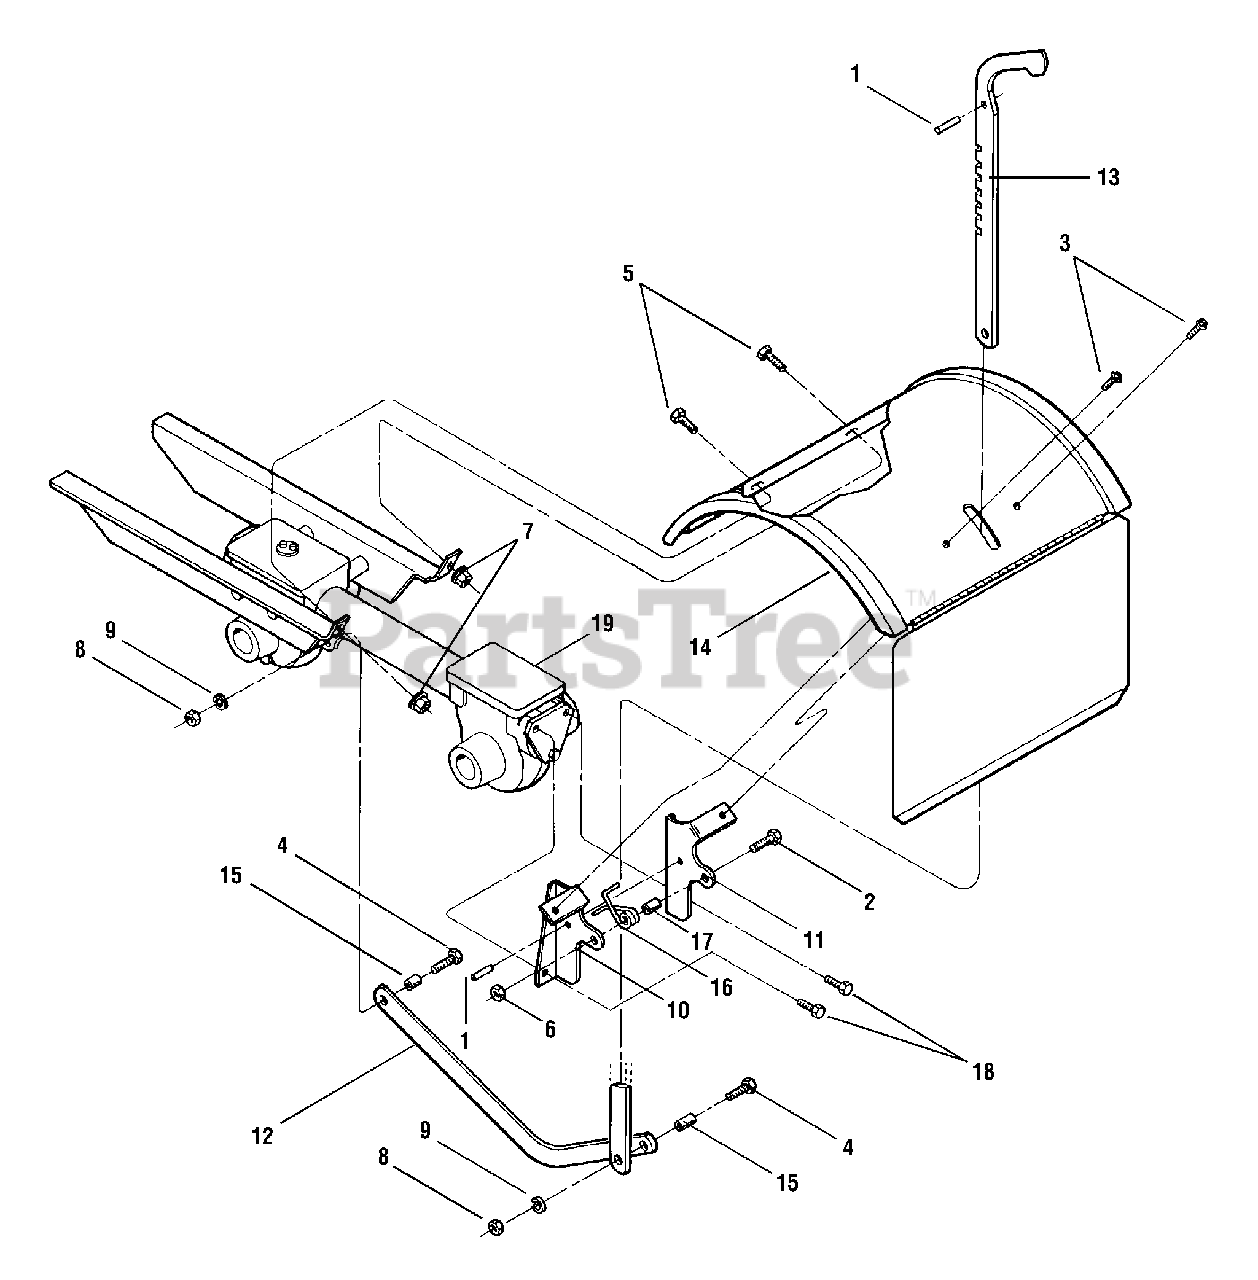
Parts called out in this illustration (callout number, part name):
1	Spirol Pin
2	Hex Hd. Screw, 1/4-20 x 1
3	Screw, Self-Tapping,1/4-20 x 1/2
4	Hex Hd. Screw, 5/16-18 x 1-1/4
5	Hex Hd. Screw, 5/16-18 x 1/2
6	Hex Lock Nut, 1/4-20
7	Hex Flange Lock Nut, 5/16-18
8	Hex Nut, 5/16-18
9	Lock Washer, 5/16
10	Hood Bracket, Left Hand
11	Hood Bracket, Right Hand
12	Drag Bar
13	Depth Regulator Lever
14	Tine Hood Assembly
16	Spring, Depth Regulator
18	Hex Hd. Flange Screw, 5/16-18 x 1
19	Transmission Assembly
